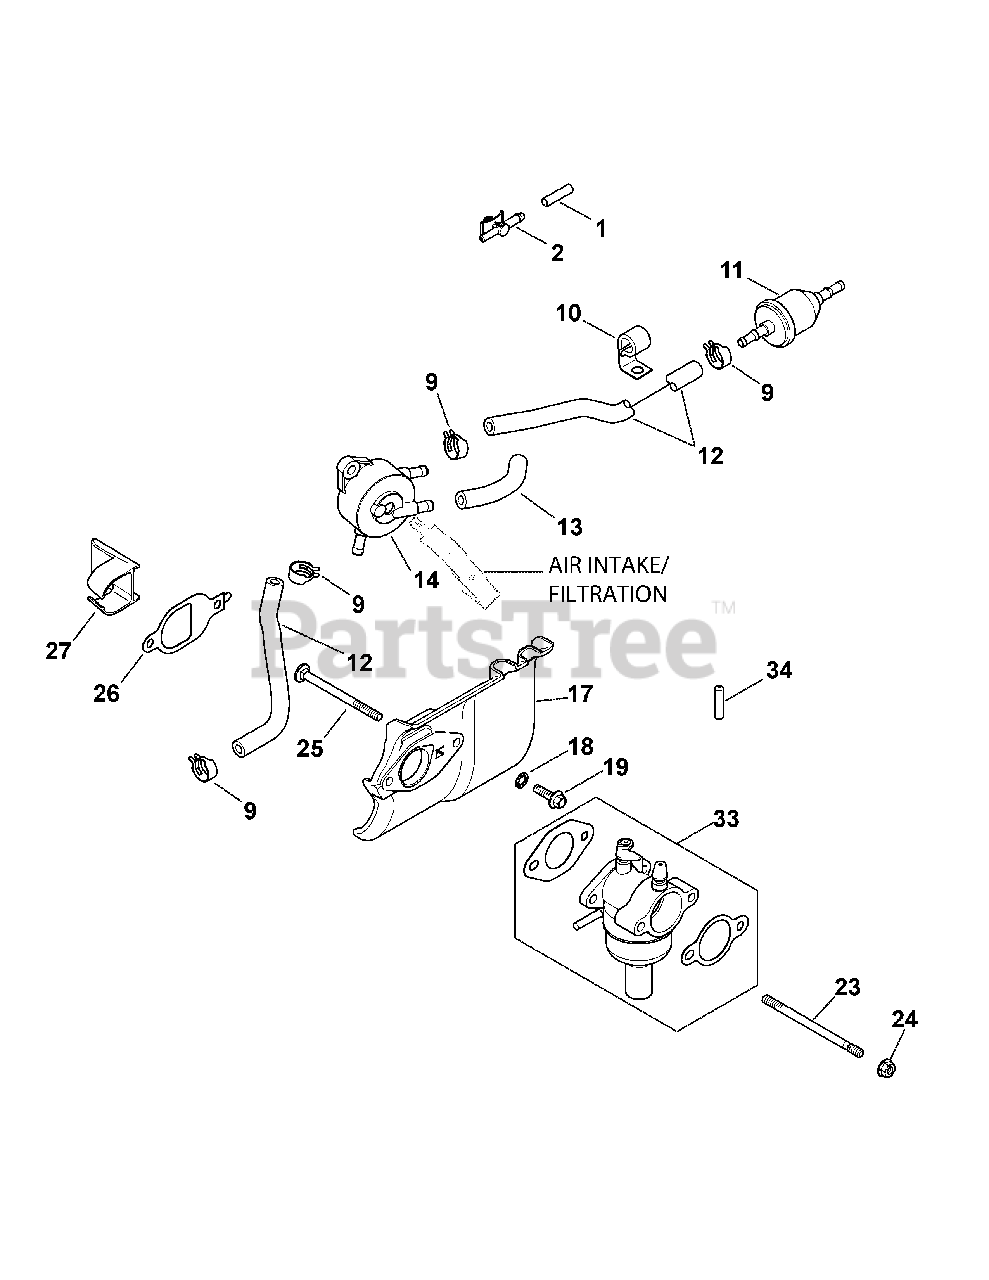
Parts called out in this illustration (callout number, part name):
2	SAI Connector
9	Hose Clamp, 1.2
12	Fuel Line
17	Heat Deflector Kit
18	Int. Tooth Lock Washer, 1.4
19	Flange Screw, M6 X 1.0 X 20
23	Stud, M6 X 1.0 X 100
24	Flange Nut, M6 X 1.0
25	Carburetor Stud
26	Heat Deflector Gasket
27	Intake Port Insert
33	Carb Tier III Walbro Kit
